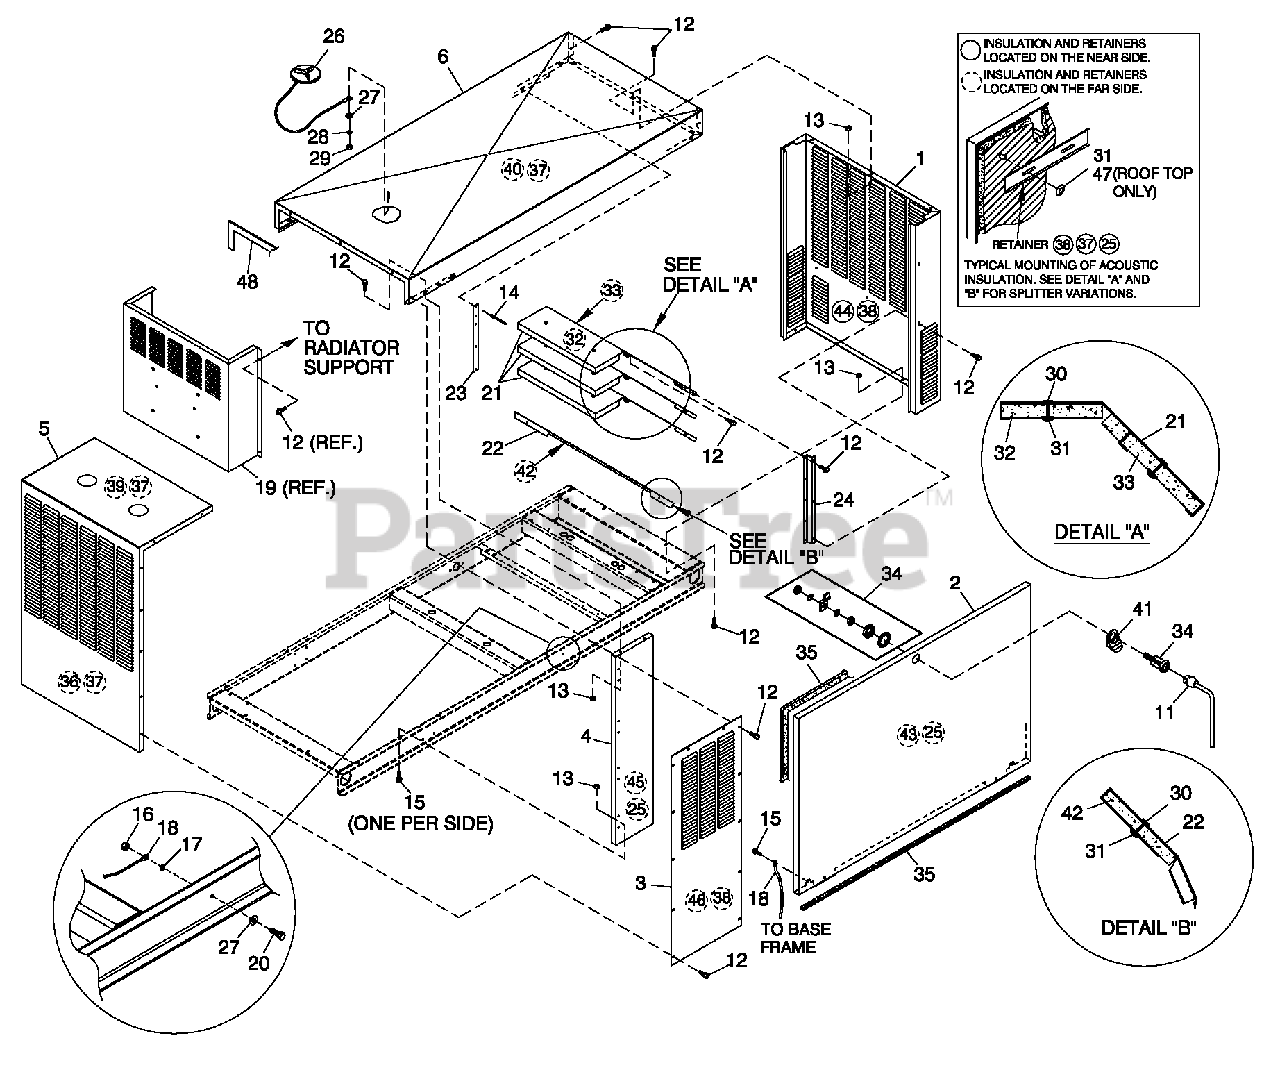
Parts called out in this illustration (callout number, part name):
1	REAR WRAP C4
2	DOOR C4
3	DISCHARGE DUCT LH & RH SIDE C4
4	FRONT CORNERS C4
5	DISCHARGE CENTER DUCT C4
6	ROOF C4ALU M
11	KEY VISE-ACTION LATCH SLOT CIR
12	SCREW THF M6-1 X 16 N WA Z/JS
13	NUT HEX LOCK M6-1.0 SS NY INS
14	RIVET POP .1875 X .450 SS
15	SCREW HWHTF M6-1.0X16
16	NUT HEXM6X1.0G8YEL CHR
17	WASHER SHAKEPROOF INT 1/4
18	ASSY WIRE 14AWG 34.8" GRN/YEL
19	INNER DISCHARGE DUCT, C4
20	SCREW HHC M6-1.0X20G8.8
21	SPLITTER C4
22	SPLITTER LOWER C4
23	STRINGER SPLITTER C3
24	SUPPORT SLITTER C4
25	RETAINER INSULATION (820)
26	ASSE MBLY COVER ACCESS
27	WASHER FLAT 1/4- M6ZINC
28	WASHER LOCK M6-1/4
29	NUT HEX 1/4-20 STEEL
30	INSULATION RETAIN MENT HANGER
31	WASHER SELF LOCKING DO ME #4-40
32	INSULATION SPLITTER
33	INSULATION LOWER SPLITTER
34	VISE-ACTION LATCH SLOTTED CIR
35	GASKET EXTRUDED TRI M (374.64" LG)
36	INSULATION DISCHARGE FRONT
37	RETAINER INSULATION (740)
38	RETAINER INSULATION (450)
39	INSULATION DISCHARGE TOP
40	INSULATION ROOFTOP
41	TAB PULL
42	INSULATION LOWER SPLITTER
43	INSULATION DOOR
44	INSULATION REAR WRAP
45	INSULATION CORNER POST
46	INSULATION DISCHARGE SIDE
47	WASHER SELF LOCKING DO ME #8-32
48	STRIP SEALANT 1/8 X 1 (44.52"LG)
